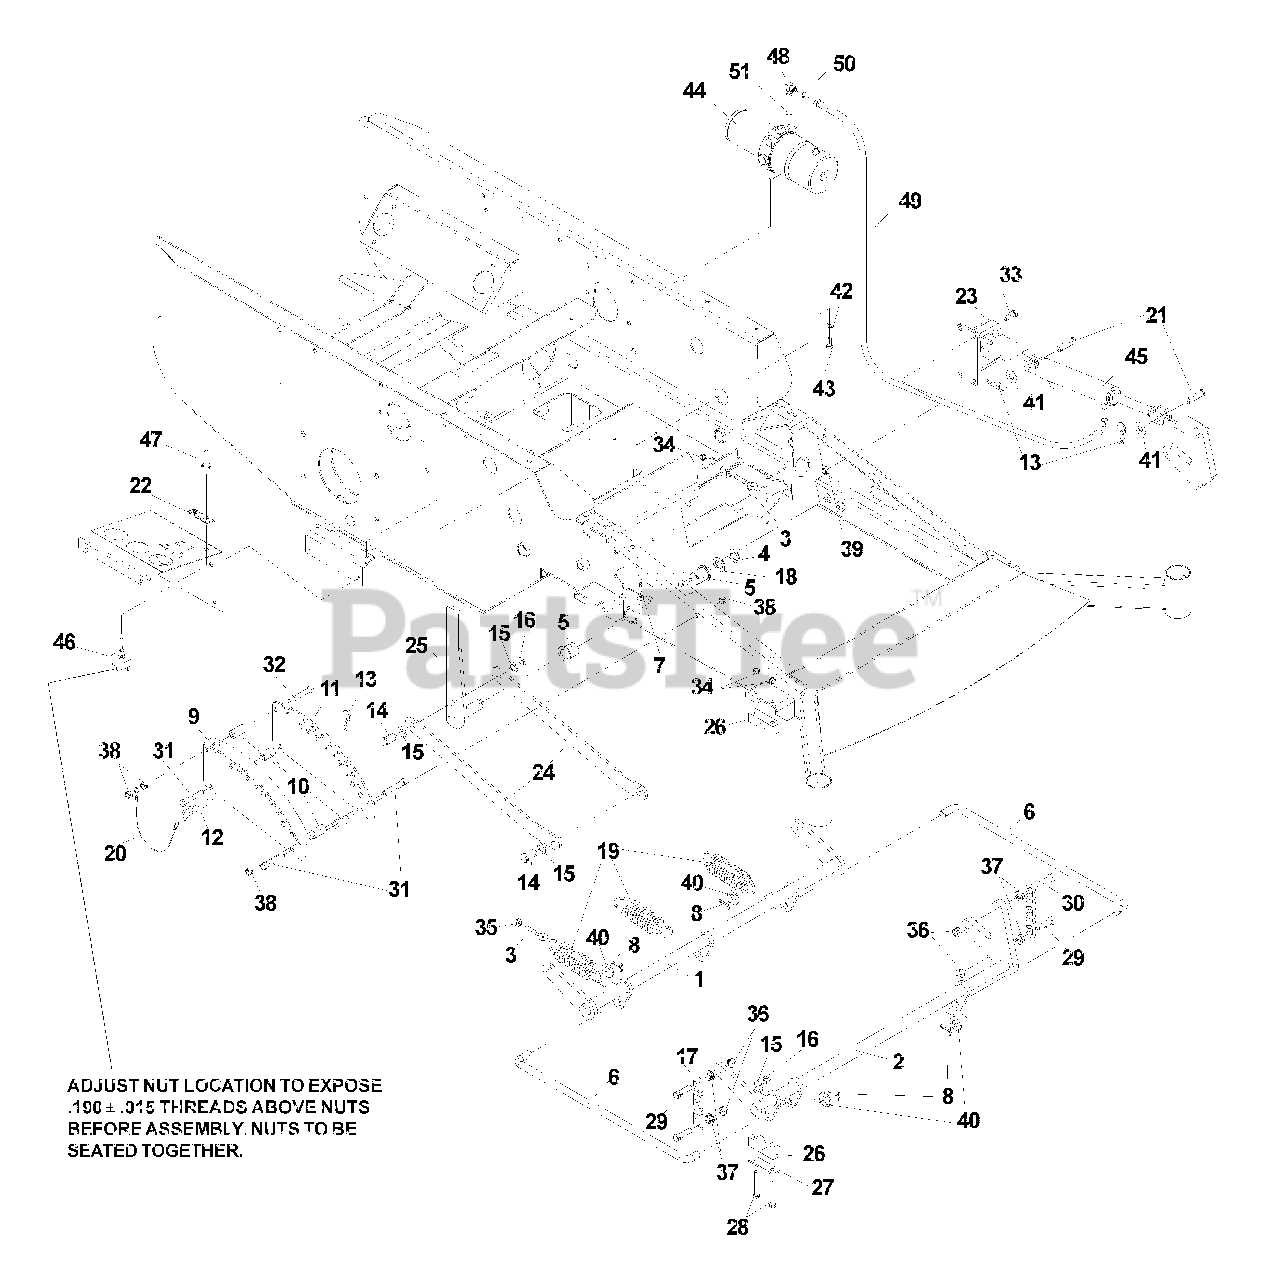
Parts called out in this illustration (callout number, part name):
1	Shaft, lift, rear
2	Shaft, lift, front
3	Eyebolt, right
4	E-ring, 7/8
5	Bushing, flanged-PM
6	Link, connecting
7	Zerk, long
8	Pin, cotter, 5/32 x 1 1/4
9	Adjustment plate
11	Adjustment plate
13	Hairpin, #4
14	Pin, clevis
15	Bushing, machine, 5/8
16	E-ring, 5/8
17	Lift chain
18	Bushing, machine, 7/8
19	Spring, extension
21	Pin, clevis, 1/2 x 1 3/4
22	Decal, lift switch
23	Cylinder mounting
24	Lift linkage
25	Lift lever
26	Pillow block
27	Bar, reinforcement
28	Bolt, 5/16-18 x 2 1/2
29	Bolt, 7/16-14 x 1 1/2
30	Bolt, 7/16-14 x 1 3/4, GR 5
31	Bolt, 3/8-16 x 2 1/4
32	Bolt, 3/8-16 x 2 1/2
33	Bolt, 3/8-16 x 1
34	Nut, 5/16-18, centerlock
35	Nut, 5/16-18, serrated washer
36	Nut, 7/16-14, centerlock
37	Nut, 7/16-14, whiz
38	Nut, 3/8-16, centerlock
39	Nut, 3/8-16, nyloc
40	Washer, 5/8
41	Washer, 1/2
42	Lockwasher, 3/8
43	Bolt, 3/8-16 x 3/4
44	Power unit/hydraulic lift
47	Switch boot
49	Hose assembly
